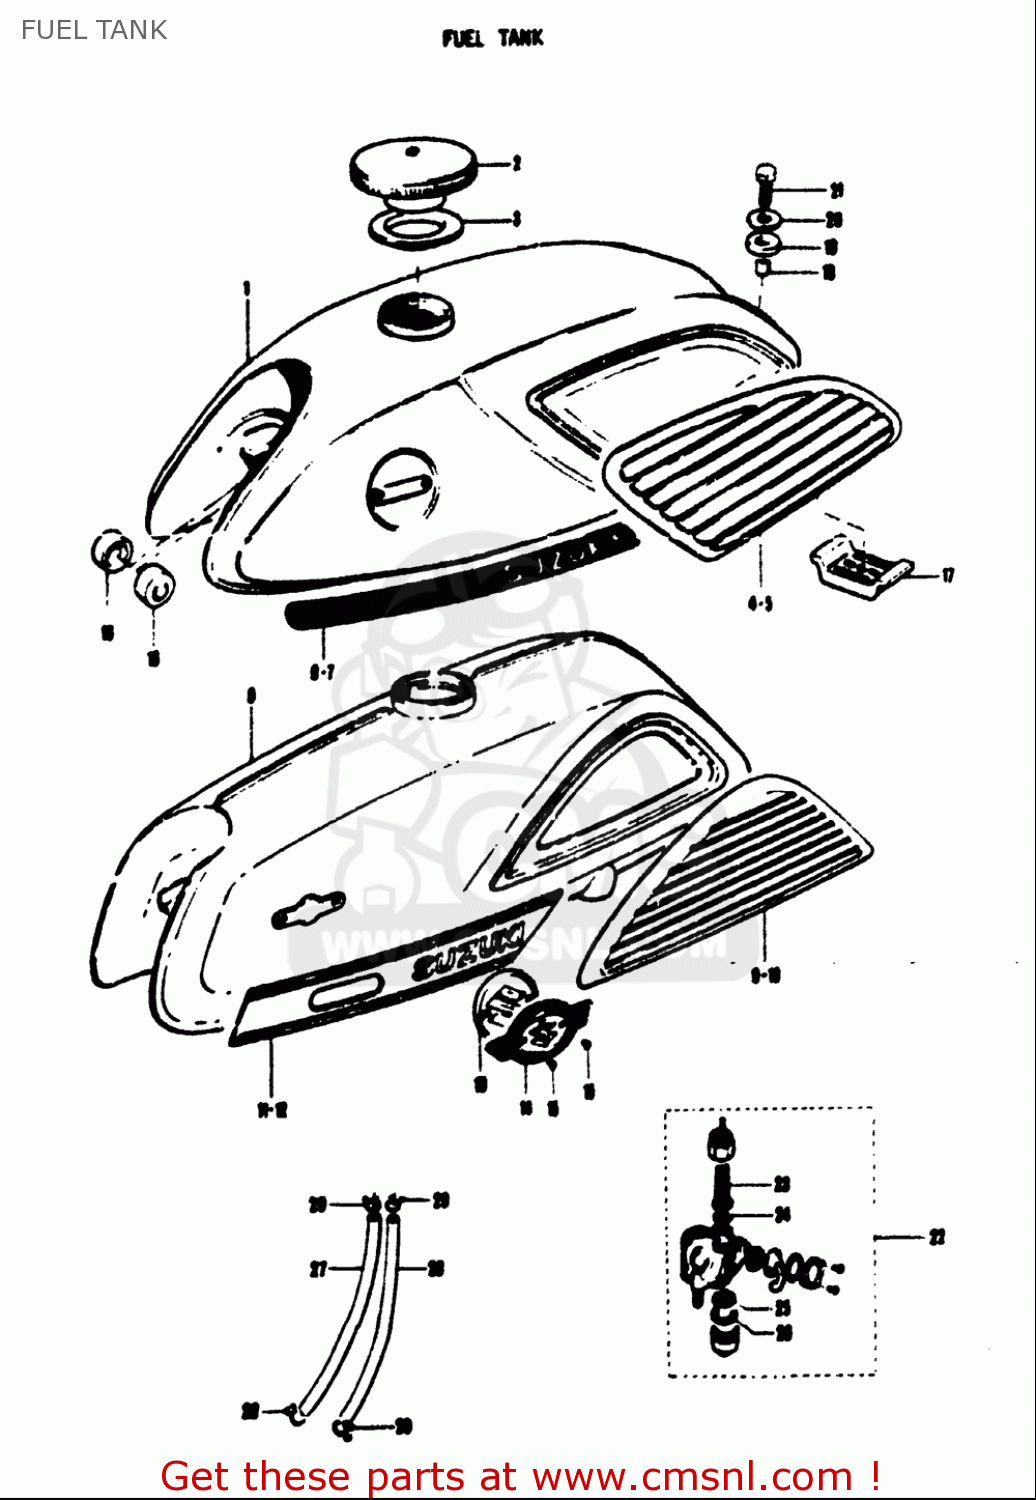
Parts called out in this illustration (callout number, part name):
2	CAP ASSY,FUEL TANK FILLER
18	SPACER (8.8X12X15.5)
19	BUSH(12X15X20)
20	WASHER(8.5X28X1.6)
21	BOLT(8X27)
24	GASKET,FUEL COCK
26	GASKET,CLEANER CUP (NAS)
28	HOSE(5X8.2X600)
30	CAP ASSY,FUEL TANK FILLER
